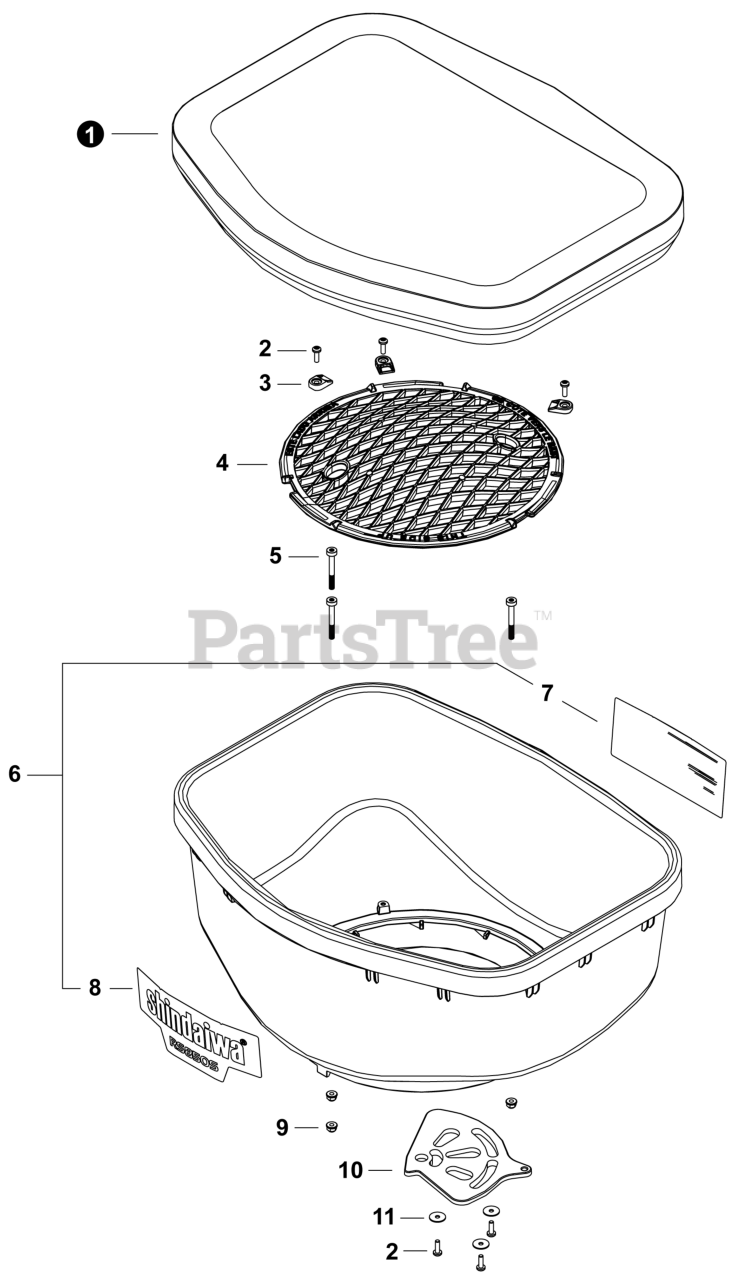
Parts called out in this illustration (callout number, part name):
1	COVER, HOPPER
2	SCREW, TAPPING 5x16
3	CLIPS, SCREEN
4	SCREEN, HOPPER
5	BOLT, M6 X 50MM
6	HOPPER ASSY
7	LABEL - OPERATION
8	LABEL - RS850S
10	PLATE, REGULATOR
11	WASHER 5 MM
